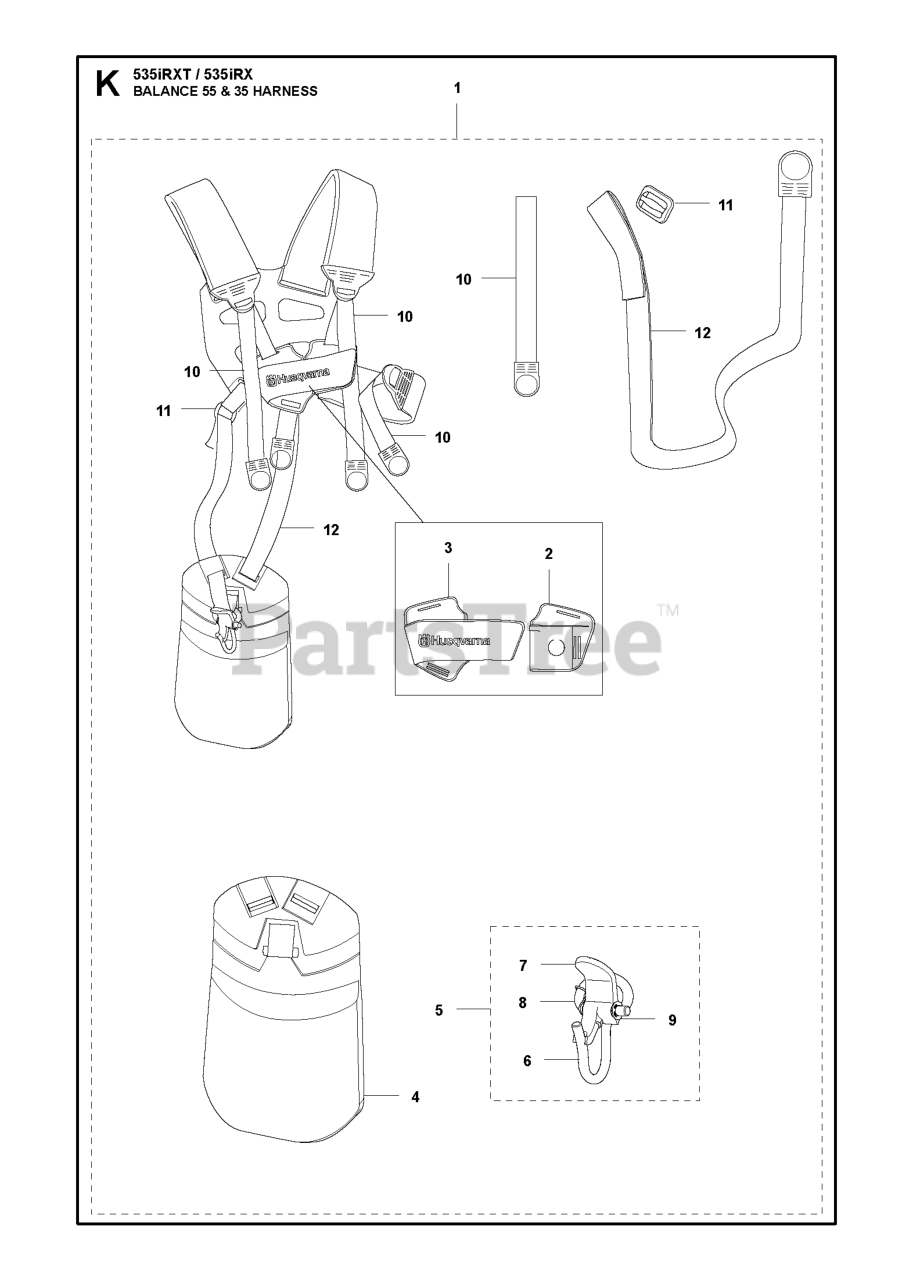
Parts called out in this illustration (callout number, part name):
1	Duo Balance Harness
1	Duo-Bal Harness
2	FRONT PIECE
3	FRONT PIECE
5	HARNESS HOOK, COMPLETE
6	HOOK
7	CATCH *
8	SPRING
